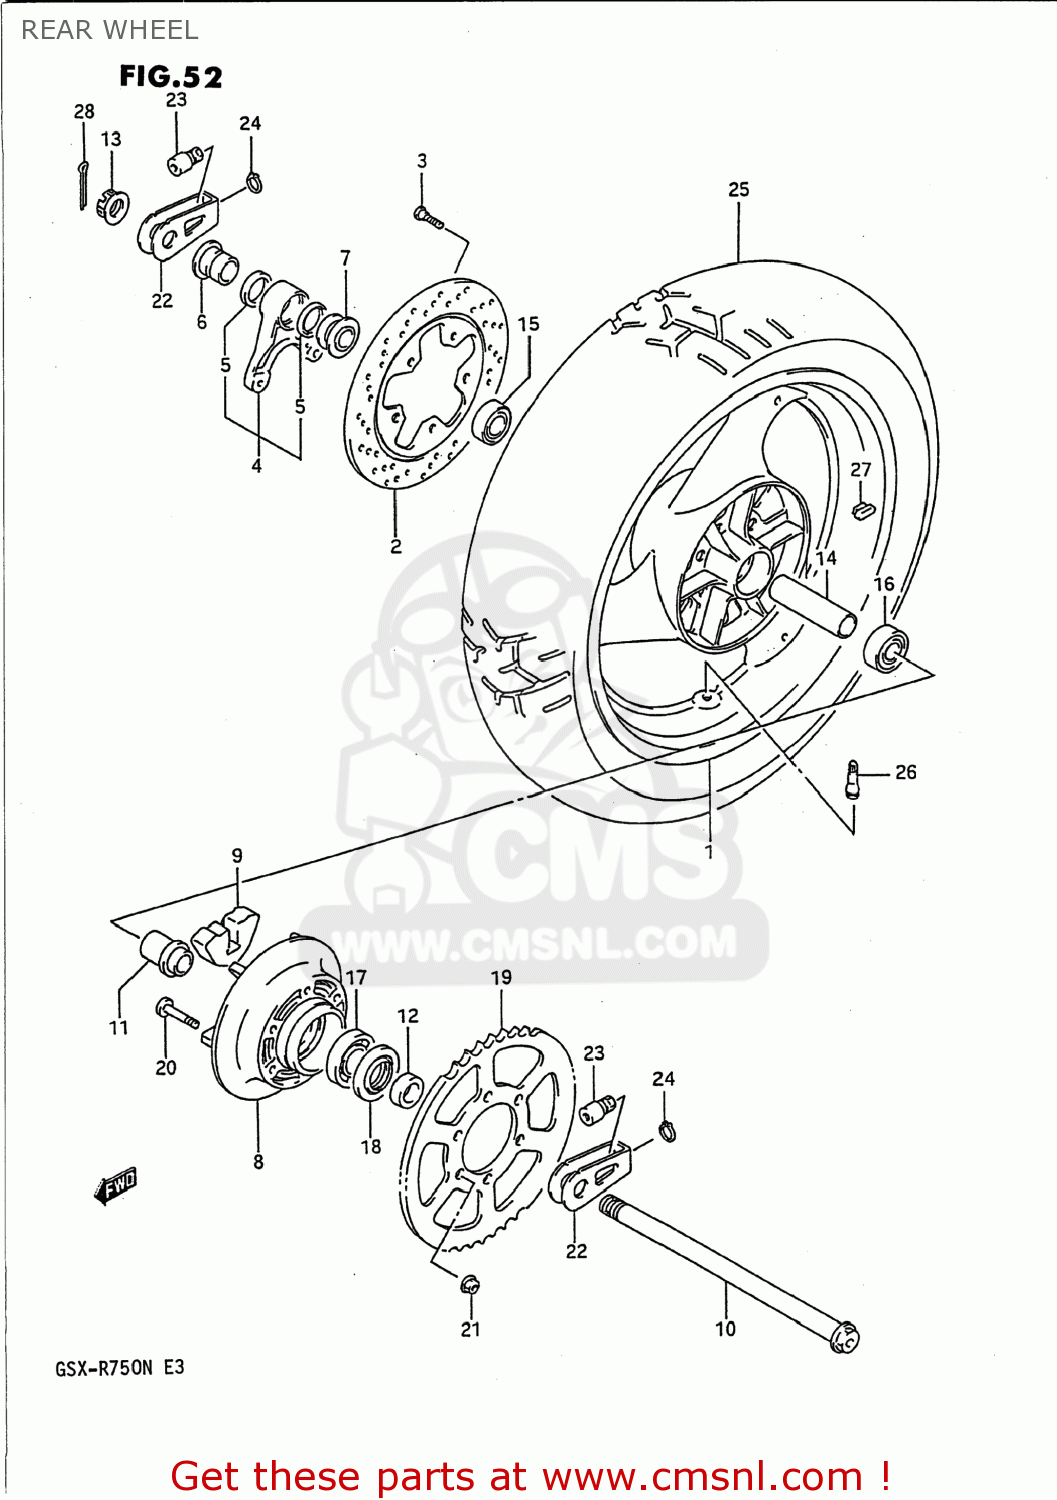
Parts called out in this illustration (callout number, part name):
1	WHEEL,REAR (17XMT5.50)
2	DISC,RR BRAKE
3	BOLT
4	BRACKET,RR CALIPER
5	SEAL,OIL(28X35X5)
6	SPACER,RR CALIPER BRACKET
7	SPACER,RR AXLE,R
8	DRUM,RR SPROCKET
9	ABSORBER,RR HUB SHOCK
10	AXLE,RR
11	RETAINER,RR HUB BEARING
12	SPACER,RR AXLE,L
13	NUT
14	SPACER,RR WHEEL HUB BEARING
15	BEARING(20X47X14)
16	BEARING(20X47X14)
17	BEARING(25X62X17)
18	SEAL,OIL(35X62X8)
19	SPROCKET,REAR
20	BOLT
21	NUT
22	ADJUSTER,CHAIN
23	ADJUSTER,CHAIN
24	CIRCLIP
25	TIRE,REAR 170/60 ZR17
26	VALVE ASSY,WHEEL RIM(TR412)
27	BALANCER,WHEEL
28	PIN, COTTER
